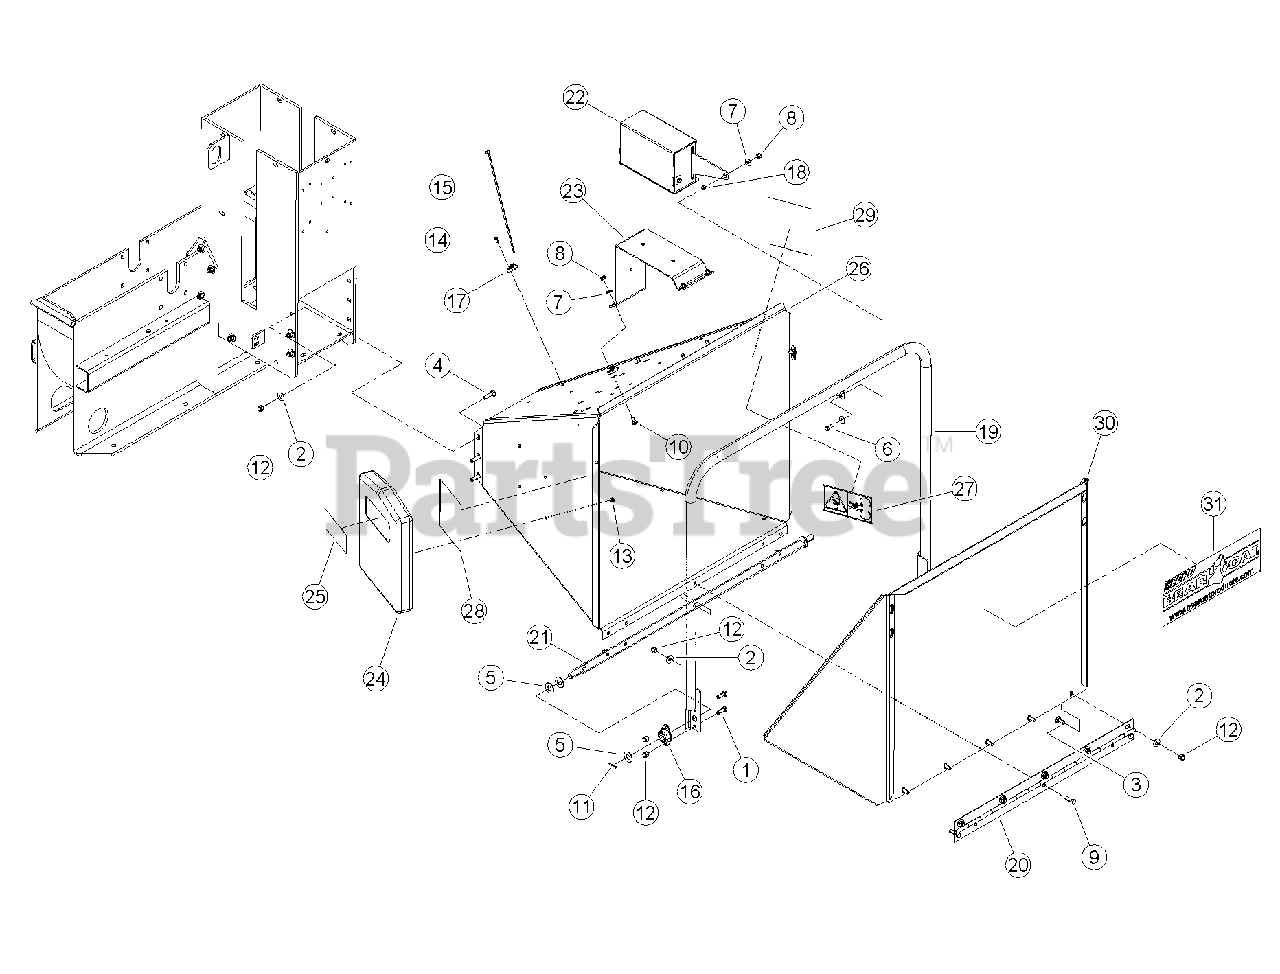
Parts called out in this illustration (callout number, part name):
1	BOLT, 3/8 X 1 HEX HD GR5 ZP
2	WASHER, 3/8 FLAT ZP
3	BOLT, 3/8 X 1 CRG GR5 ZP
4	BOLT, 3/8 X 1-1/2 CRG GR5 ZP
5	WASHER, 5/8 SAE FLAT ZP
6	BOLT, 5/16 X 1 HHCS GR5 NC ZP
7	WASHER, 5/16 FLAT ZP
8	NUT, 5/16 NE NYLOCK ZP
9	BOLT, 3/8 X 1-1/4 HEX HD GR5 ZP
10	BOLT, 5/16 X 3/4 CRG GR5 NC ZP
11	PIN, 1/8 X 1.00 ZP COTTER
12	NUT, 3/8 NE NYLOCK ZP
13	RIVET, AL BLIND 1/4 X 1/2 DOME HEAD
14	RIVET, AL BLIND 1/4 X 3/4 DOME HEAD
15	STRAP, 11 INCH BLACK TIE
16	BEARING, SIDE FLNG MOUNT 5/8"
17	CLAMP, CABLE MOUNT
18	SPACER, IDLER PIVOT
19	WELDMENT, CONTROL ARM
20	HINGE, EXTENSION TRAY
21	WELDMENT, CONTROL PIVOT
22	ASSEMBLY, SWITCH BOX
23	MOUNT, SWITCH BOX
24	ASSEMBLY, MANUAL CONTAINER SERVICE PART
25	DECAL, MUTILINGUAL MANUAL
26	ASSEMBLY, BIG CHIPPER CHUTE SERVICE PART
27	DECAL, BLADE DANGER ISO
28	DECAL, FEED POSITION
29	DECAL, FEED POSITION
30	ASSEMBLY, CHUTE EXTENSION TRAY SERVICE PART
31	DECAL, BEARCAT WEB
